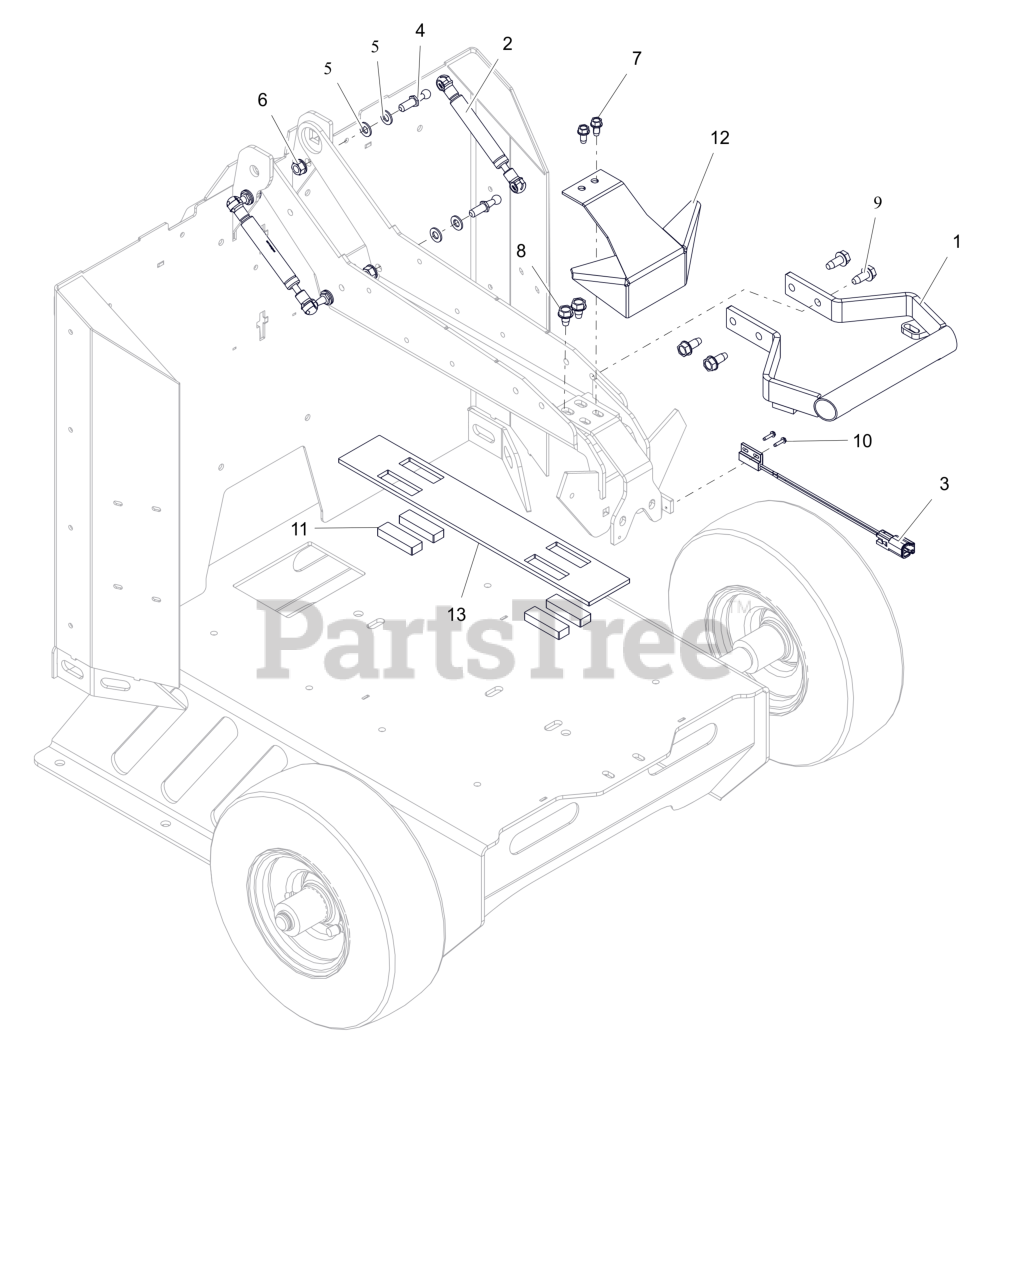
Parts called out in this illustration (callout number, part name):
1	WLDMT, HANDLE (BLUE)
2	DAMPER, GAS
3	SWITCH, MAGNETIC
4	STUD-BALL-THREADED
5	WSHR,FLT .323X.625X.062 ZCC
6	NUT,LK-CTR-FLG .31-18 GF ZCC
7	SCR-TAP .25-20X.50 HWH ZCC
8	SCR,TAP .312-18X.50 HWH TR ZCC
9	SCR,TAP .312-18X.75 HWH TR ZCC
10	SCR-TAP #4-40x.50 HWH ZCC
11	PAD, RUBBER
12	COVER, LATCH (BLUE)
13	PAD, RUBBER
